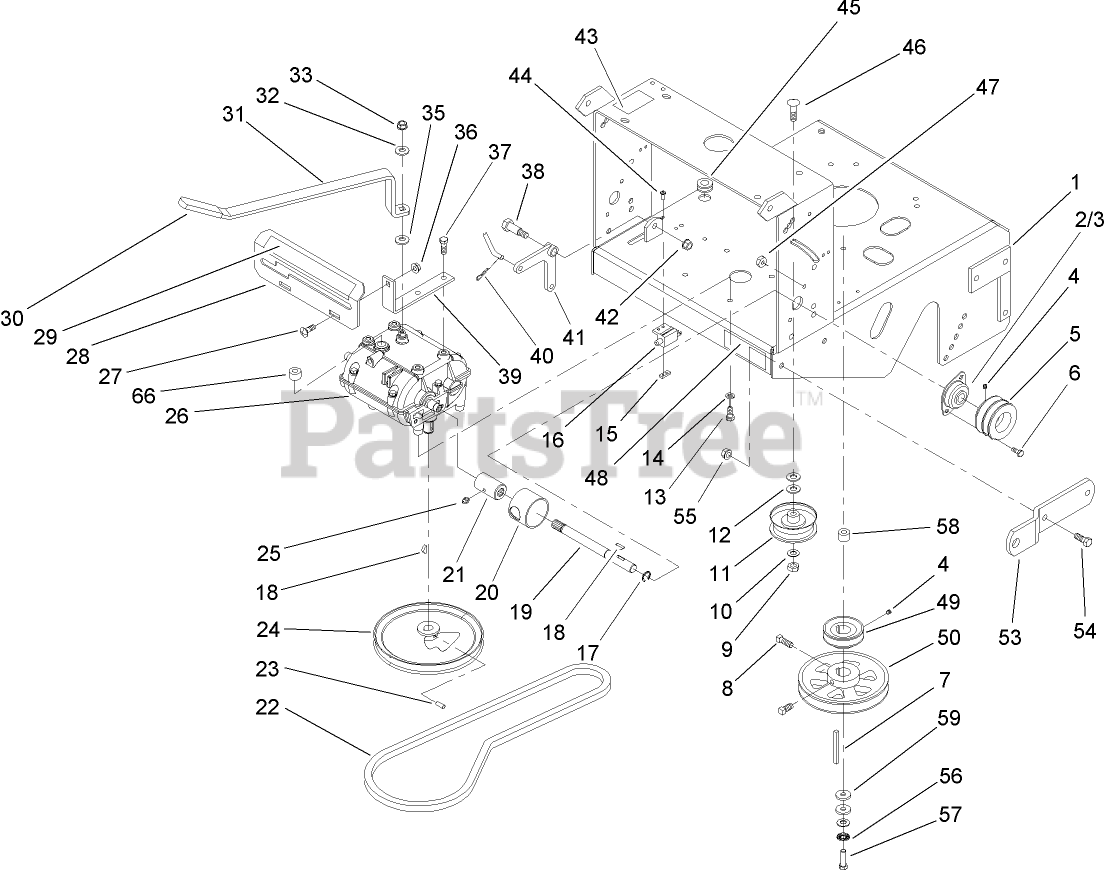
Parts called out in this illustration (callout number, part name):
1	FRAME-DECK, REAR
2	BEARING-SHAFT
3	FLANGE-OUTPUT
4	SCREW-SET
5	SHEAVE-TRANSMISSION
6	SCREW-HH
8	SCREW-SET, SQH
9	NUT-LOCK, NI
10	WASHER-FLAT
11	PULLEY-IDLER, FLAT
12	WASHER-FLAT
13	SCREW-HH
14	WASHER-LOCK
15	PLATE-TAPPED
16	SWITCH-OPEN, NORMALLY
17	RING-RETAINING
18	KEY-WOODRUFF
19	SHAFT-TRANSMISSION
20	GUARD-COUPLER
21	COUPLER
22	V-BELT
23	SCREW-HSH
24	SHEAVE-TRANSMISSION
25	FITTING-GREASE
26	TRANSMISSION
27	BOLT-CARR
28	PLATE-SHIFT
29	DECAL-SPEED, GROUND
30	GRIP-LEVER
31	LEVER-SHIFT
32	WASHER-BELLEVILLE
33	NUT-LOCK
35	WASHER
36	NUT-HF
37	SCREW-HWH, THREAD CUT
38	BOLT-SHOULDER
39	BRACKET-PLATE, SHIFT
40	PIN-COTTER
41	BELLCRANK
42	NUT-HHF, WHIZ
43	DECAL-SHUT OFF, FUEL
44	SCREW-PPH
45	GROMMET
46	SCREW-CARR
47	NUT-LOCK, NI
48	DECAL-CAUTION
49	Sheave-Transmission
50	SHEAVE
53	HITCH-SULKY
54	SCREW-HH
55	NUT-HHF, WHIZ
56	WASHER-SPRING
57	SCREW-HH
58	SPACER-CLUTCH
59	WASHER
66	Switch-Start, Neutral
